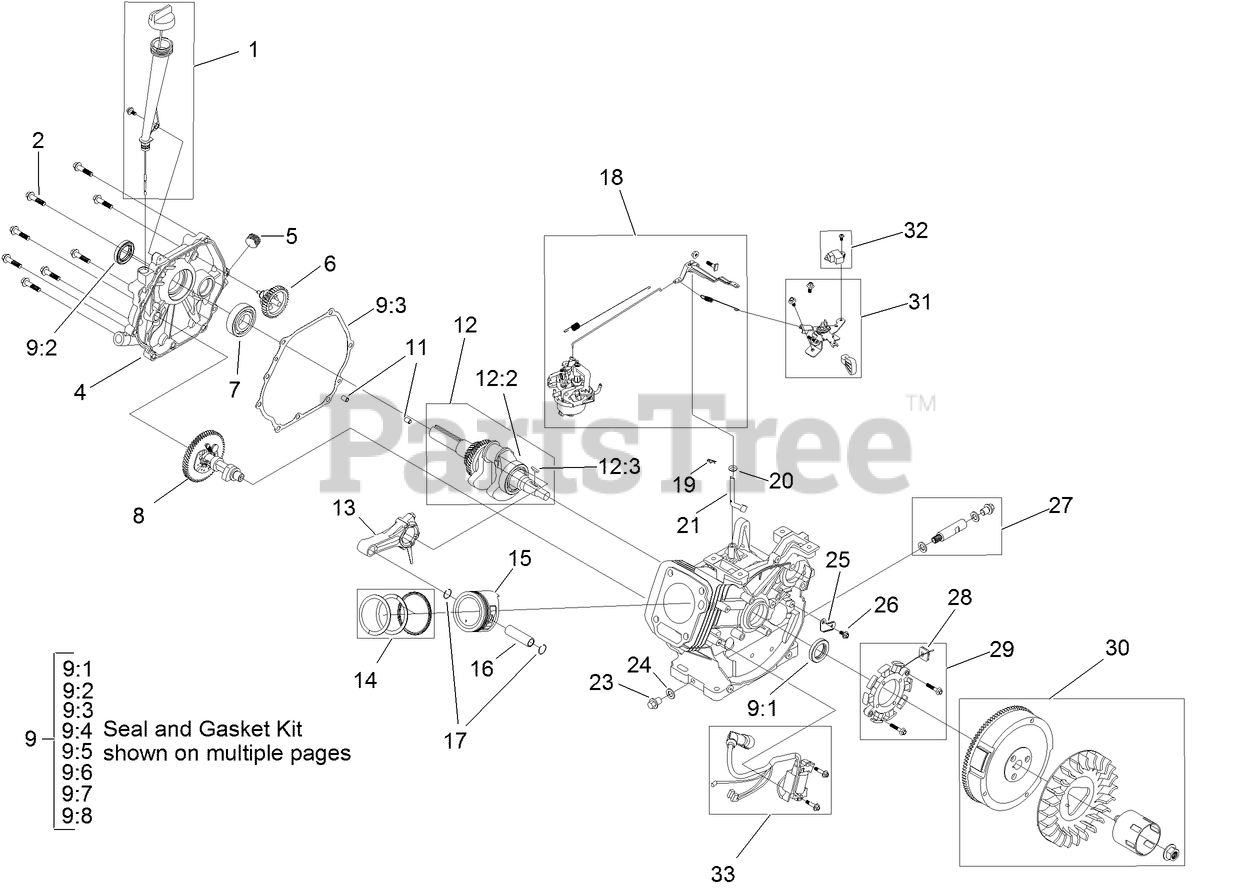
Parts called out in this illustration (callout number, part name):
1	OIL FILL KIT
2	SCREW-HHF
4	COVER-CRANKCASE
5	PLUG-DRAIN
6	GOVERNOR GEAR ASM
7	BEARING-MAIN
8	CAMSHAFT ASM
9	SEAL AND GASKET KIT
9:1	SEAL-OIL
9:2	SEAL-OIL
9:3	GASKET-COVER, CRANKCASE
9:4	GASKET-HEAD, CYLINDER
9:5	GASKET-COVER, VALVE
9:6	GASKET-EXHAUST
9:7	GASKET-CARBURETOR
9:8	GASKET-CARBURETOR
11	PIN-DOWEL
12	CRANKSHAFT ASM
12:2	BEARING-MAIN
12:3	KEY-WOODRUFF
13	CONNECTING ROD ASM
14	SET-RING, PISTON
15	PISTON
16	PIN-PISTON
17	CLIP-PIN, PISTON
18	COMPLETE GOVERNOR KIT
19	PIN-HAIR
20	WASHER-PLAIN
21	SHAFT-GOVERNOR
23	SCREW-HHF
24	WASHER-PLAIN
26	SCREW-HHF
27	DRAIN PLUG KIT
28	GROMMET-RUBBER
29	STATOR KIT
30	FAN AND FLYWHEEL KIT
31	THROTTLE CONTROL KIT
32	KILL SWITCH KIT
33	IGNITION KIT
